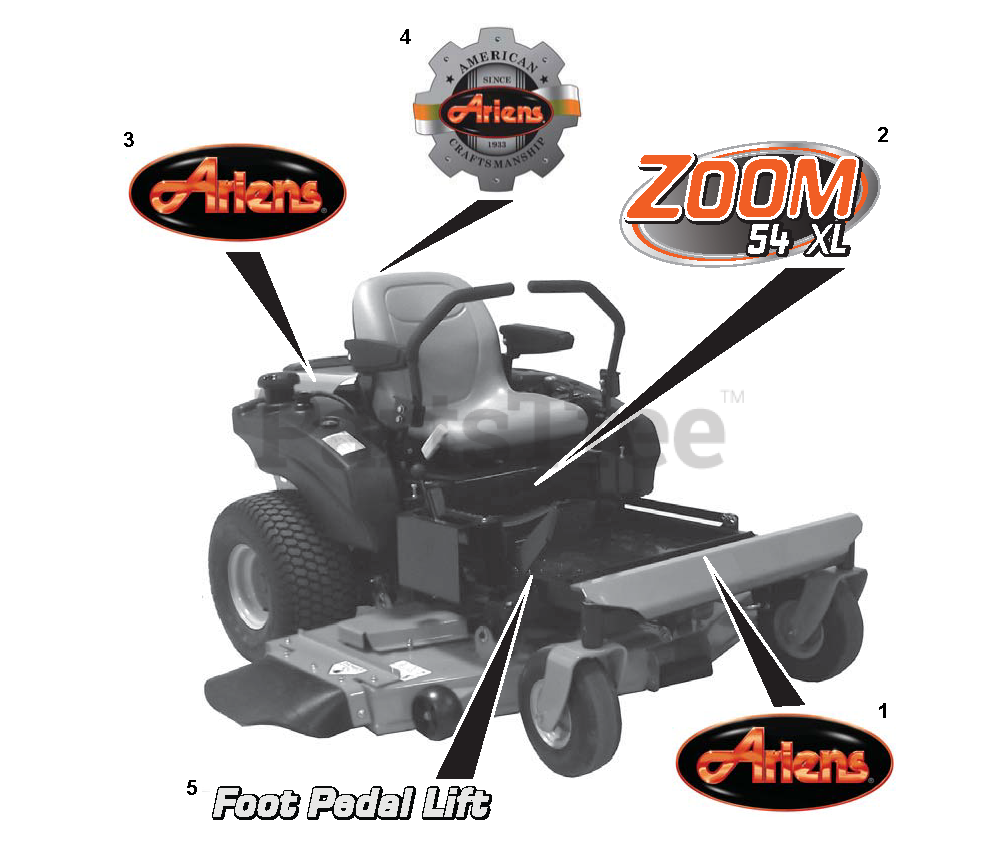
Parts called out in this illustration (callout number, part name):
1	DECAL, ARIENS JEWEL
2	DECAL,ZOOM 42 XL
3	DECAL, ARIENS JEWEL
4	Decal, Ariens American Heritage
5	DECAL, FOOT PEDAL LIFT
